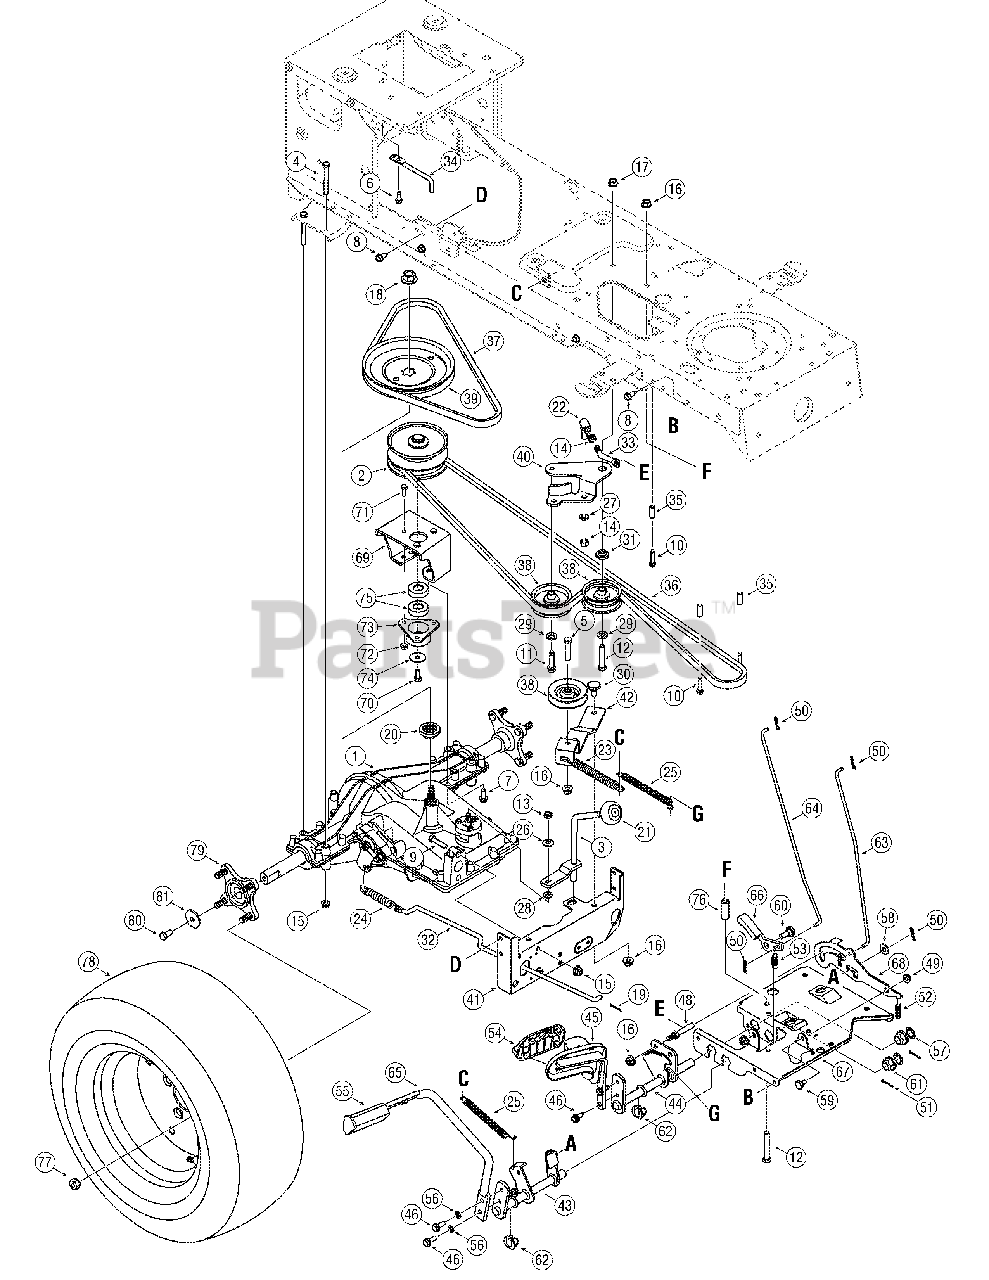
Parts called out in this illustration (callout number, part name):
1	Transmission Assembly, 2-Speed
2	Variable Speed Pulley Assembly
3	Rod Assembly, Shift, 2-Speed
4	Screw, 5/16-18, 2.75, Gr5
5	Screw, 3/8-16, 1.75, Gr5
6	Screw, 1/4-20, 0.750
7	Screw, 5/16-18, 0.875
8	Screw, 5/16-12, 0.750
9	Screw, 5/16-18, 1.50, Gr5
10	Screw, 1/4-20, 1.250
11	Screw, Sems, 3/8-16, 1.500
12	Screw, 3/8-16, 2.25, Gr5
13	Nut, Jam Lock, 3/6-16
14	Nut, Hex, 3/8-24, Gr5
15	Nut, Flange Lock, 5/16-18
16	Nut, Flange Lock, 3/8-16
17	Nut, Flange Lock, 3/8-16, GrF,
18	Nut, Flange, 7/16-20, Gr2
19	Pin, Cotter, 3/32 x.750
20	Hub, Pulley, 1/2 Spline
21	Knob, Shift
22	Ball, Joint
23	Extension, Spring 6.12
24	Spring, Extension,.59 OD x 4.00
25	Spring, Extension,.50 Dia x 6.37
26	Washer, Bell,.375 x.870 x.063
27	Washer, Lock, 3/8, Regular Duty
28	Washer, Flat,.44x.75x.06, Ht Spcl
29	Washer, Flat,.407x.812x.135, Ht
30	Screw, Shoulder,.625 Dia x.217
31	Spacer, Shoulder, 1.00 x.38 x.38
33	Adjustment Rod, Idlr, 3/8
34	Rod, Belt Guard
35	Spacer,.260 x.372 x 1.030
36	Belt, V-Type
37	Belt, V-Type
38	Pulley, Flat Idler, 2.75
39	Pulley, V-Type, 8.50
46	Screw, 5/16-18, 0.750
47	Screw, 5/16-18, 0.750
48	Pin, 3/8-16 x 2.68
49	Nut, Flange Lock, 5/16-18, Gr5
50	Pin, Cotter,.072 Dia. x 1.13
51	Pin, Cotter, 3/32, 1.0
52	Spring, Compression,.405 x 1.17
53	Spring, Extension,.50 OD x 1.41
54	Pad, Drive Control
55	Pad, Brake
56	Washer, Lock, 5/16, Regular Duty
57	Washer, Flat,.64 x 1.24 x.06
58	Washer, Flat,.385 x.870 x.092
59	Shoulder Screw.437 Dia x.162
60	Screw, Shoulder,.50 x.27, 3/8-16
61	Bearing, Hex Flange
62	Bearing, Hex Flange,.628 ID, Split
63	Control Rod, Brake Lock
64	Control Rod, Cruise
66	Latch, Cruise
68	Bracket, Lockout
69	Pulley Bracket
70	Screw, 5/16-24,.75
71	Screw, 1/4-20,.75
72	Nut, Flange Lock, 1/4-20
73	Bearing Cup
74	Washer, Flat, .330 x 1.25 x .06
75	Ball Bearing
76	Spacer,.385 x.635 x 1.54
77	Lug Nut, 7/16-14
79	Wheel Hub Assembly
80	Hex Head Screw, 3/8-16
81	Washer, Flat, .390 x 1.50 x .134
